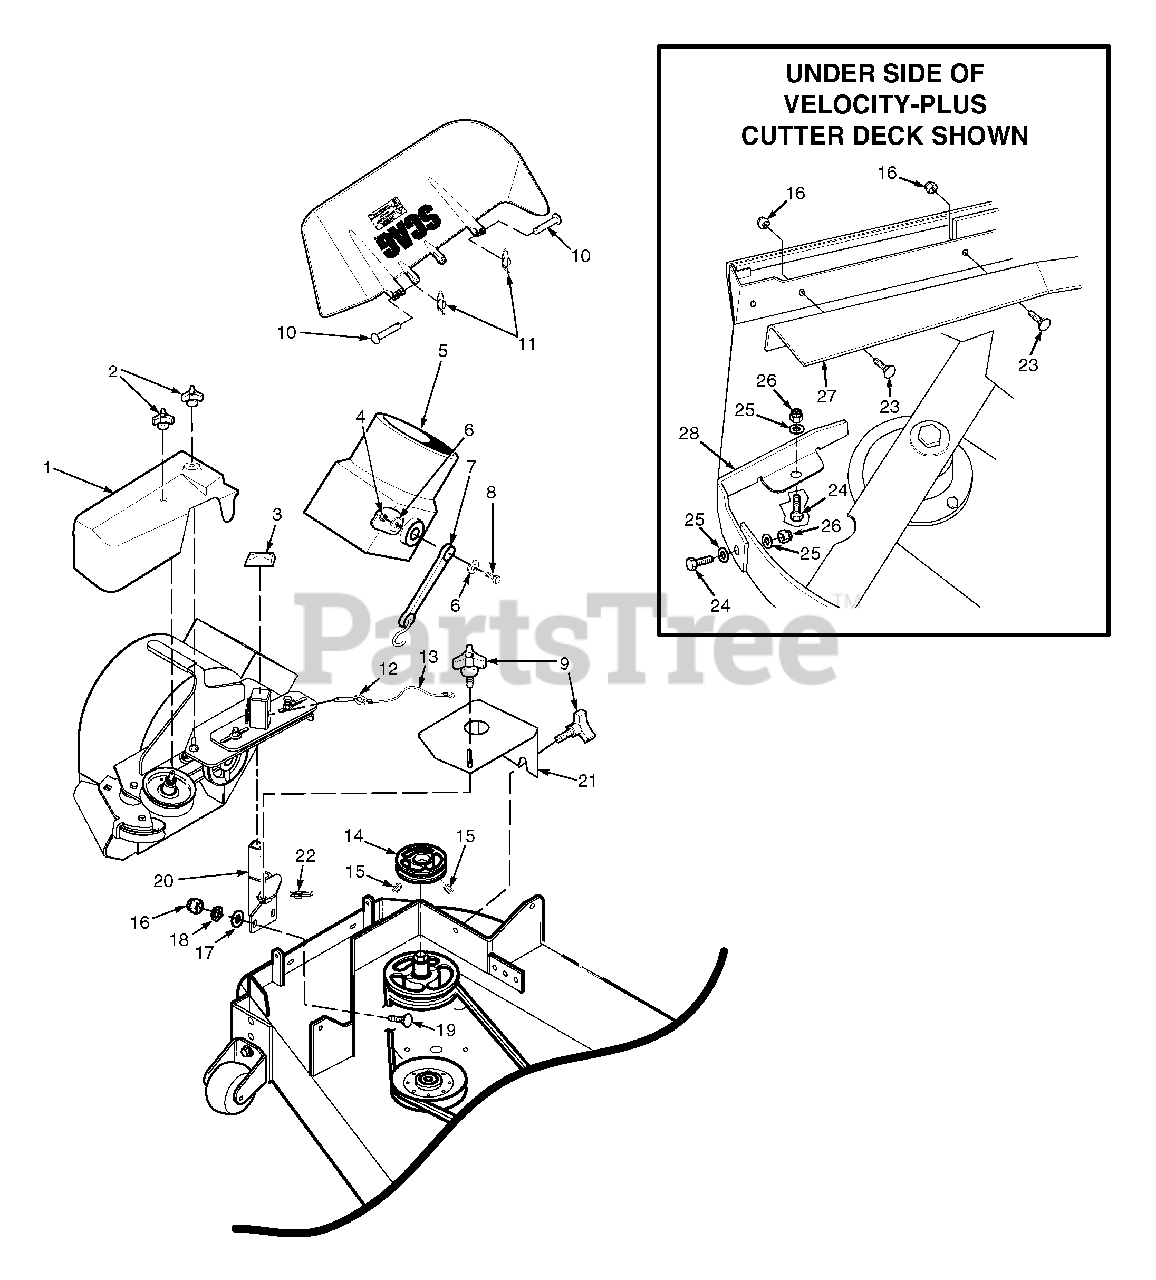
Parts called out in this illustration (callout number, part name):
1	Belt Cover, GC-61V
2	Wingnut, Plastic 3/8" Small
3	Cap, Square Vinyl
4	Nut, Elastic Stop 1/4-20
5	Adapter, Blower GC-STC,
6	Flatwasher, 1/4-.312 x .750 x .065
7	Rubber Strap 7-3/4"
8	Bolt, Hex Head 1/4-20 x 1-1/4"
9	Knob W/Stud, 3/8-16 x 1-1/4"
10	Clevis Pin, 5/16 x 1-1/2"
11	Pin, Rue Cotter 5/16 Dia.
12	Pin, Ring 1/2 x 2-1/4"
13	Lanyard
14	Pulley, 5-1/2" Dia. 1.125 Bore
15	Setscrew, 5/16-18 x 3/8"
16	Nut, Elastic Stop 3/8-16
17	Lockwasher, 3/8"
18	Flatwasher, 3/8-.391 x .938 x .105
19	Bolt, Carr. 3/8-16 x 1-1/4" Grade 5
20	Mounting Post Weldment, Blower
21	Belt Cover, GC-61V
23	Bolt, Carriage 3/8-16 x 1"
24	Bolt, Hex Head 5/16-18 x 1"
25	Flatwasher, 5/16-.375 x .875 x .083
26	Nut, Elastic Stop 5/16-18
27	Baffle, Front 61" Deck
28	Baffle, Turbo 61" Deck
